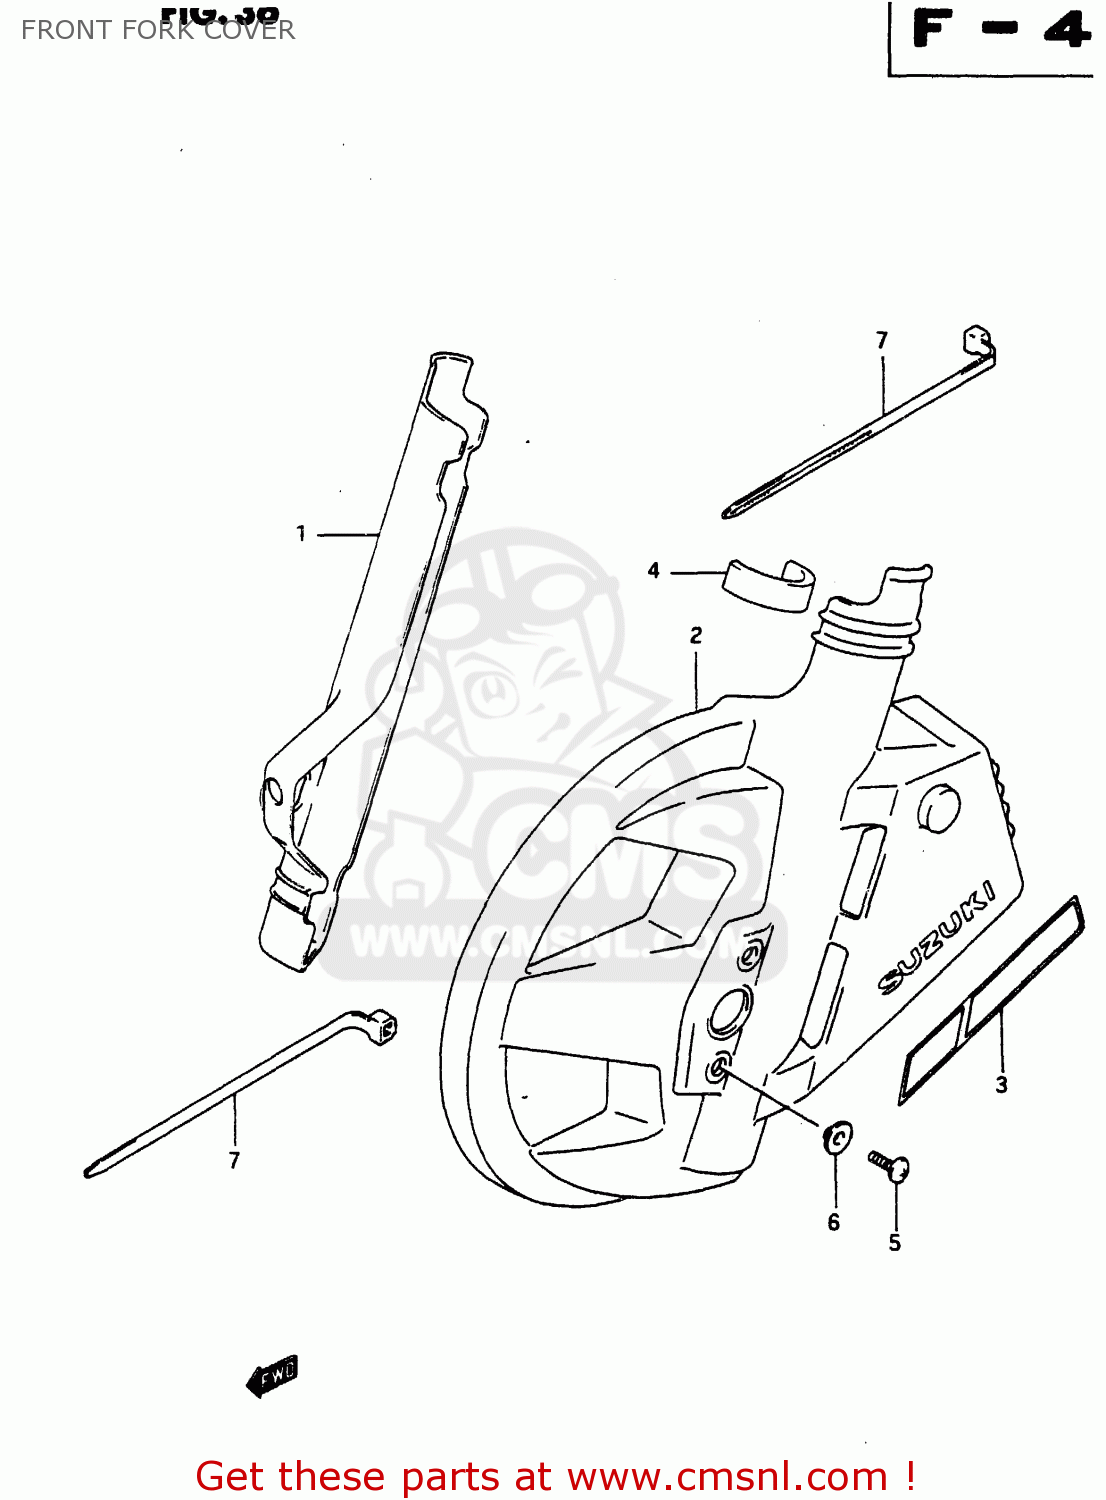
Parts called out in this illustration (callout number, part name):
1	PROTECTOR, FORK RH (WHITE)
2	PROTECTOR,FRONT FORK,LEFT
3	TAPE SET, DISC PROTECTOR
4	CUSHION
5	SCREW 6X12
6	WASHER
7	CLAMP
